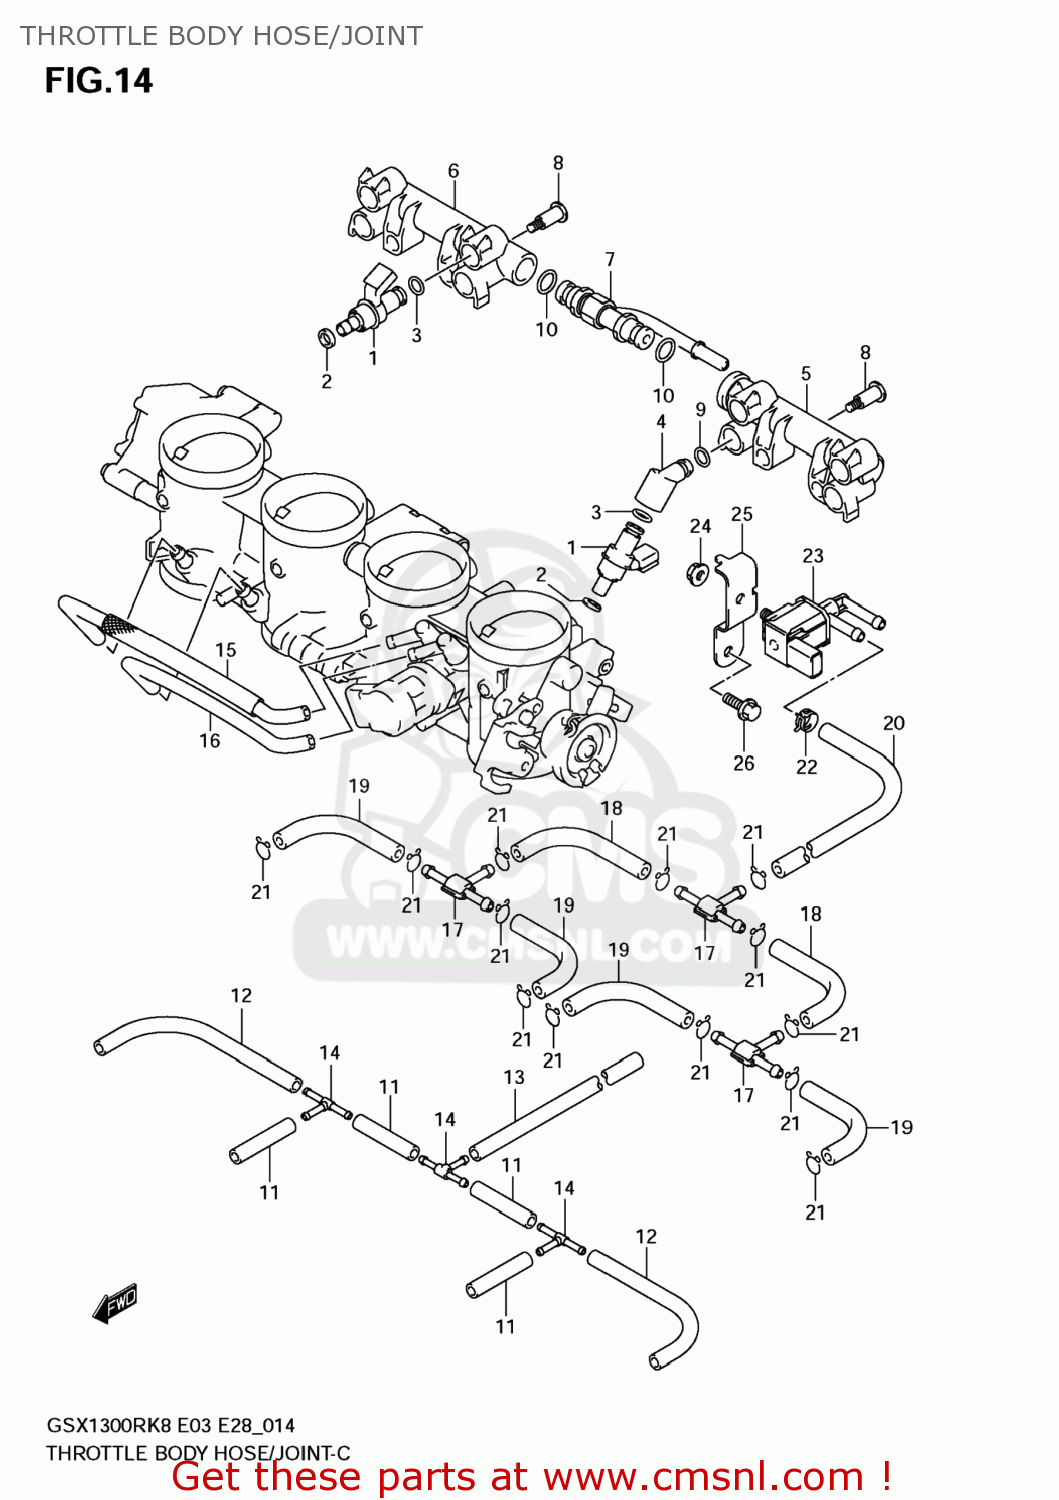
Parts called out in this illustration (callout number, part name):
1	INJECTOR ASSY
2	RING,SEAL
3	O RING
4	PIPE,FUEL
5	PIPE,FUEL
6	PIPE,FUEL
7	JOINT
8	SCREW
9	O RING
10	O RING
11	HOSE,RUBBER(L:35)
12	HOSE,RUBBER(L:100)
13	HOSE,RUBBER(3X7X170)
14	JOINT
15	TUBE
16	TUBE
17	JOINT
18	HOSE
19	HOSE
20	HOSE
21	CLIP
22	CLIP
23	VALVE,CANISTER PURGE
24	NUT
25	BRACKET,SOLENOID VALVE
26	BOLT
